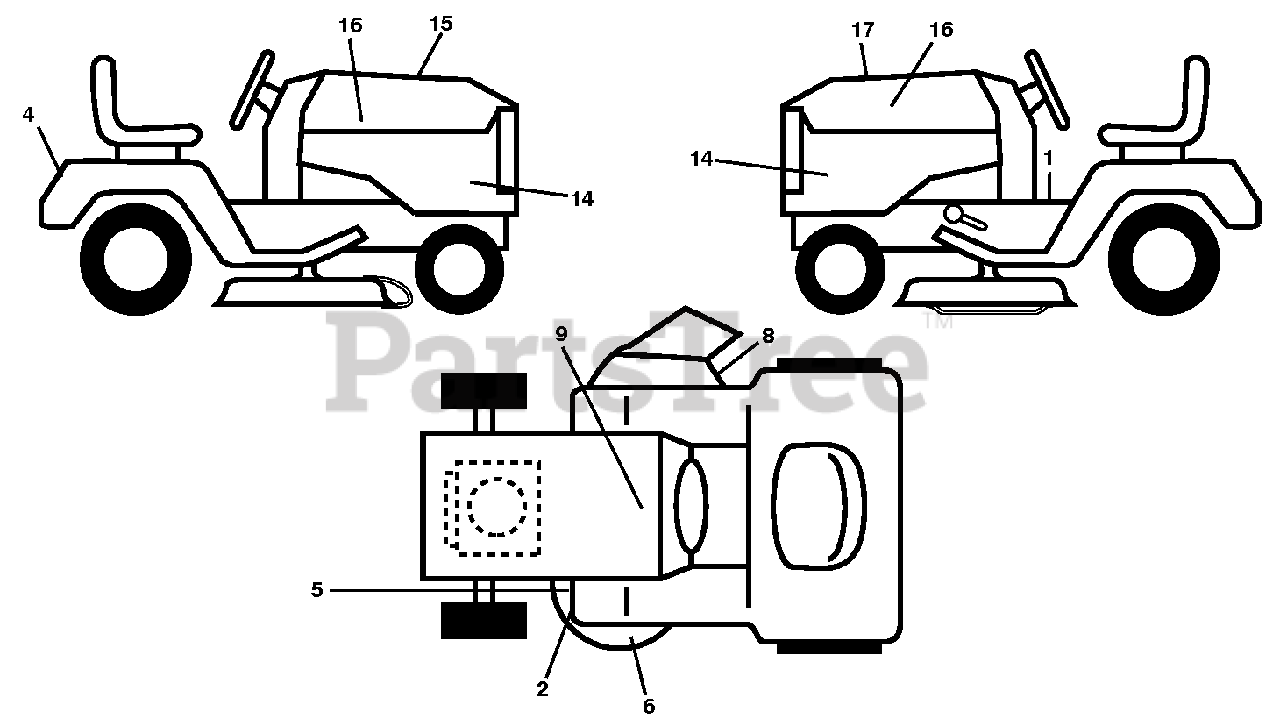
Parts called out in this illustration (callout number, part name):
1	DECAL.WARN.STARTINST.LOWEARIEN
2	DECAL.MOWER.WARN.KEEP.HAND.AWY
4	DECAL.FENDER
5	DECAL.MOWER.CAUTION.TENSION.AR
8	DECAL.MOWER.SCH.48/54.PREM
9	DECAL BTRY SYMBOLS
14	DECAL.SIDE.PANEL.LGT2654.2013
15	DECAL.WARNING.CUST.RESP.E85.
16	DECAL.BADGE.170MM.TEXTLOGO.
17	DECAL.RPL.KH.KT7000.TGW.54.K46
18	DECAL.BYPASS.FENDER.CRD/LT/YT
19	DECAL.E85.WARNING.2012
20	PAD.FOOTREST.HUSQ.GT.LH.GREY
21	PAD.FOOTREST.HUSQ.GT.RH
